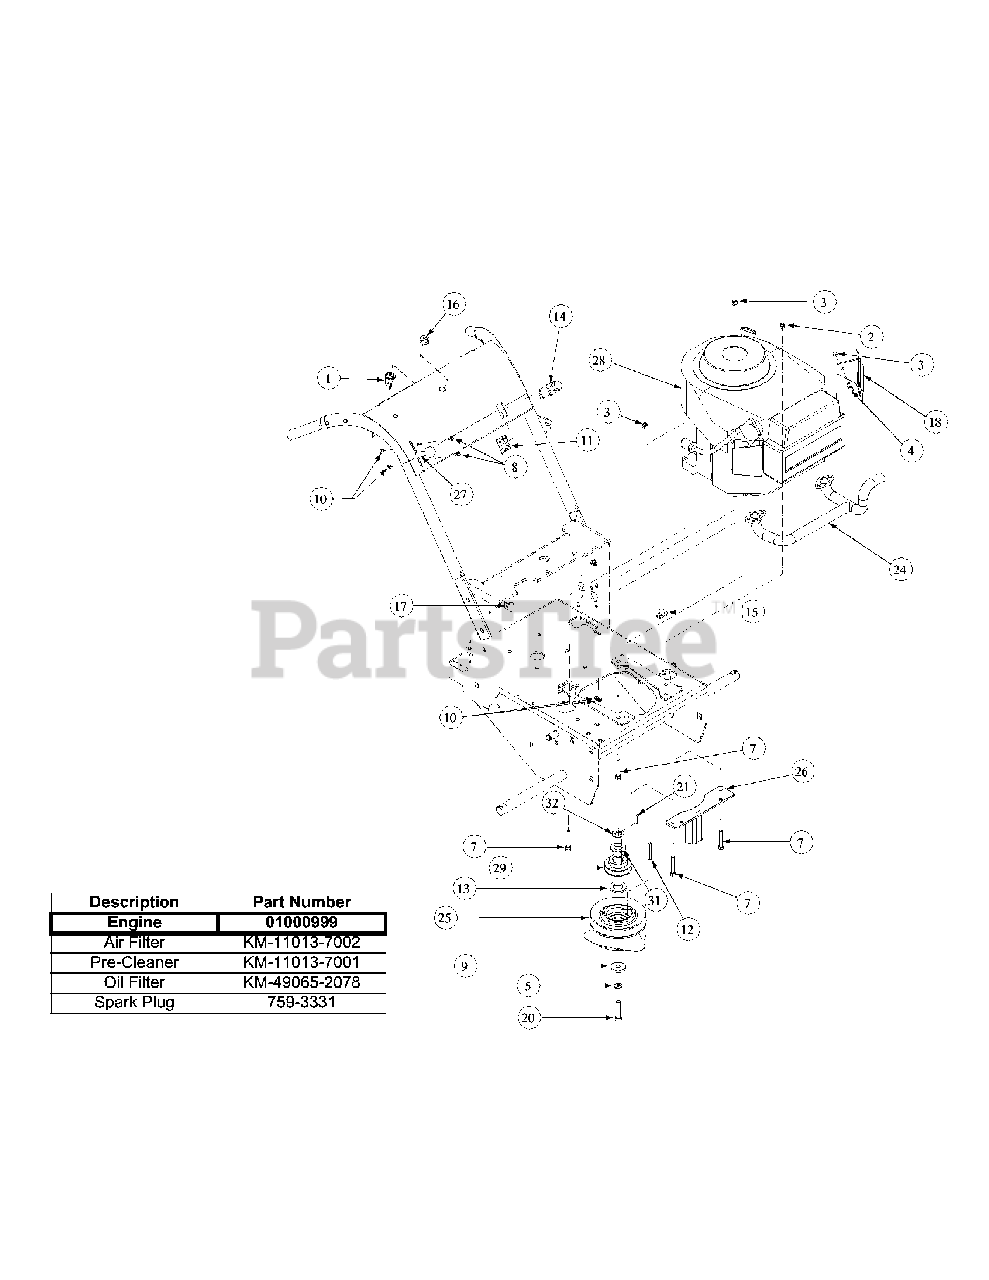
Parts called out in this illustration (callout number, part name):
1	Single Ignition ON/OFF Switch
2	Lock Nut, 5/16-18
3	Nylock Nut, 5/16-18
4	Hex Cap Screw, 5/16-18x3/4
5	Lock Washer
7	Hex Cap Screw, 5/16-18 x 2
8	Screw, Hex Washer, 10-32 x 1/2
9	Clutch Washer
10	Lock Nut, Nylon Insert, 10-32
11	Retainer Clip
12	Key Stick, 1/4 x 1/4 x 2
13	Special Washer
14	Blade Clutch Switch
15	Support Clamp, 1/2" Tubing
16	Nut, w/Cap, 5/8-32 Ignition
17	Support Clamp, 3/8 OD
18	Muffler Bracket, Kawasaki
19	Muffler Clamp Assembly
20	Capscrew, 7/16-20 x 2.5
21	Keystock, 1/4 x 1/4 x 1
22	Belt
24	Kawasaki Manifold
25	Electric Clutch
26	Clutch Retainer Bracket Assembly
27	Control Throttle w/detent
28	Kawasaki Engine, 17V
29	Gear Transmission Pulley
30	Kawasaki, Harness Assembly Gear w/electric clutch
31	Flat Washer
32	Spacer Engine Pulley, 12.5 Vanguard
